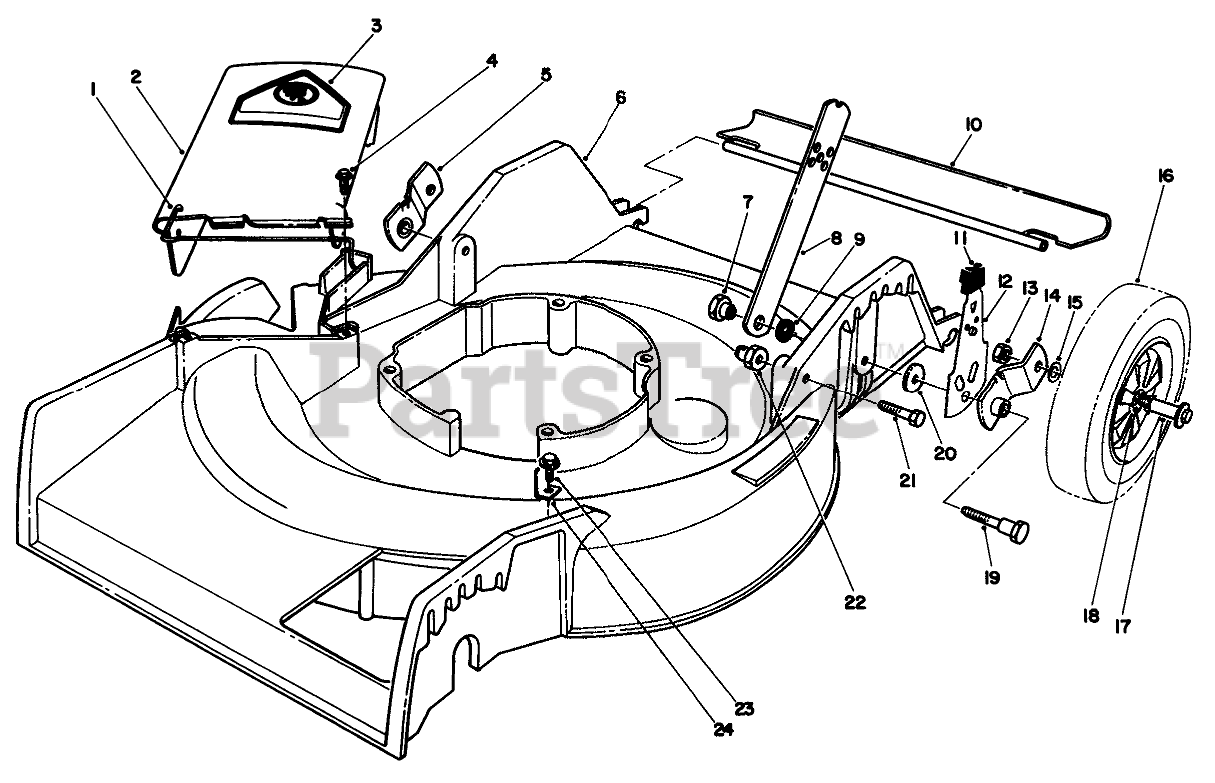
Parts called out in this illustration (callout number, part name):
1	SPRING HINGE
2	Deflector (Incl. Ref. #1 & 3)
3	DECAL-DANGER
4	SCREW-HWH
5	Pivot Arm
6	HOUSING W/CARTON
7	HANDLE PIVOT NUT
8	HANDLE LATCH
9	SPACER
10	SHIELD - TRAILING
11	KNOB-ARM
12	REAR SPRING ARM ASM
13	Nut
14	Pivot Arm
15	WASHER
16	Wheel & Tire Assembly (Incl. Ref. #18)
17	BOLT-WHEEL
18	BUSHING
19	PIVOT SCREW
20	PIVOT WASHER
21	SCREW-HH
22	HANDLE PIVOT NUT
23	SCREW-HWHTF
24	BELT GUIDE
